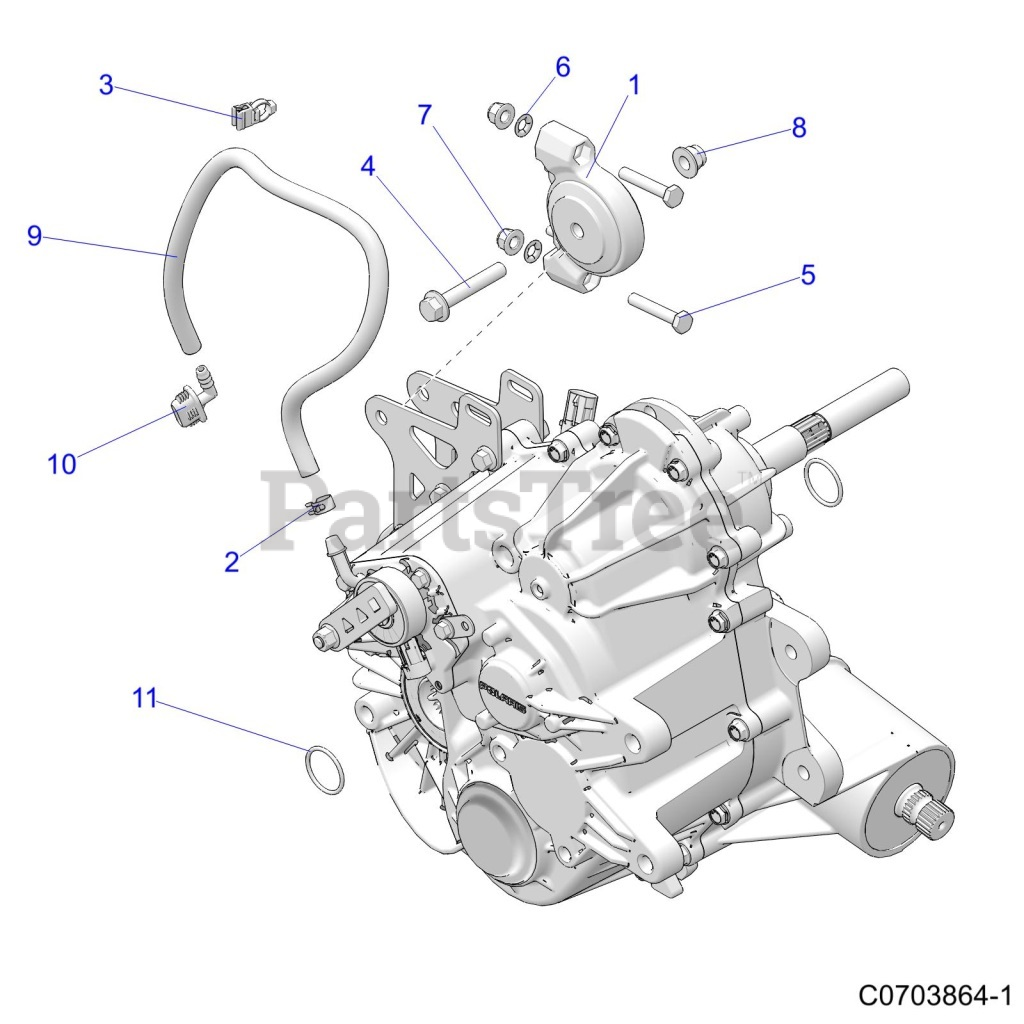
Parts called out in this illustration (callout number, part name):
1	MOUNT-ISOLATOR,DRIVELINE
2	CLAMP-HOSE, 17/32, GREEN
3	STRAP-CABLE TIE W/EDGE CLIP
4	BOLT-M10X1.25X60,HXFLG-OLIVE D
5	SCR-HH M8X1.25X45 8.8 ZOD
7	NUT-M8X1.25,FLG,NYLOC-OLIVE D
8	NUT-M10X1.25,FLG,NYLOC-OLIVE D
9	FUEL LINE-50 CM
10	FITTING-VENT LINE,90
11	O-RING,-123
